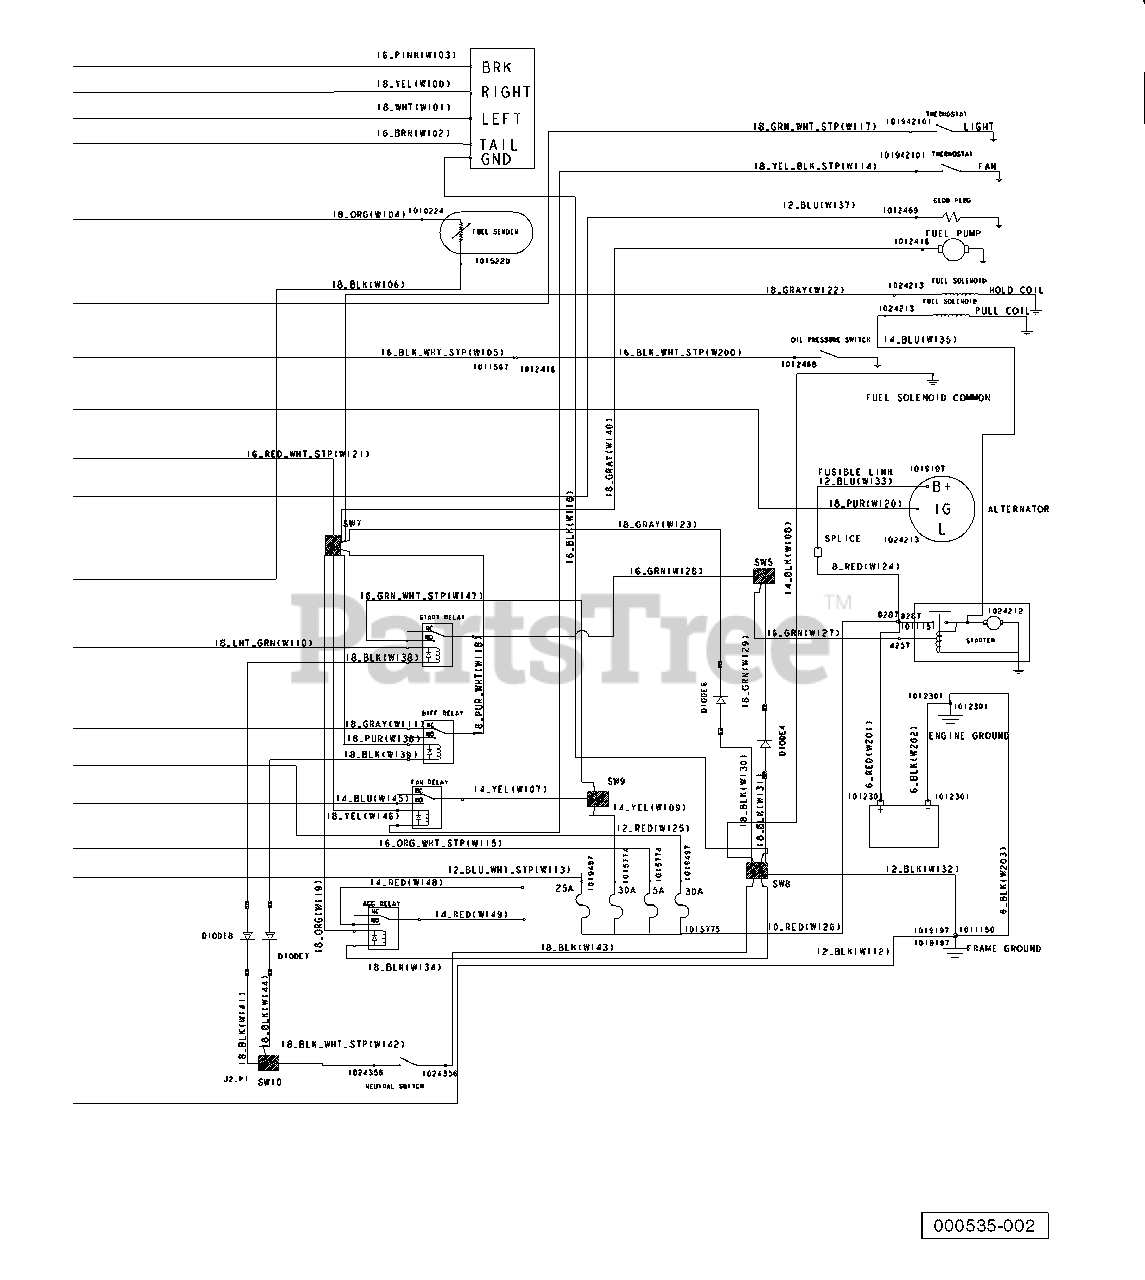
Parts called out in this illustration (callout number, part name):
1	Harness, Restyle Diesel, Front
2	Harness, Restyle Diesel, Rear
3	Asm, Switch, Limit
